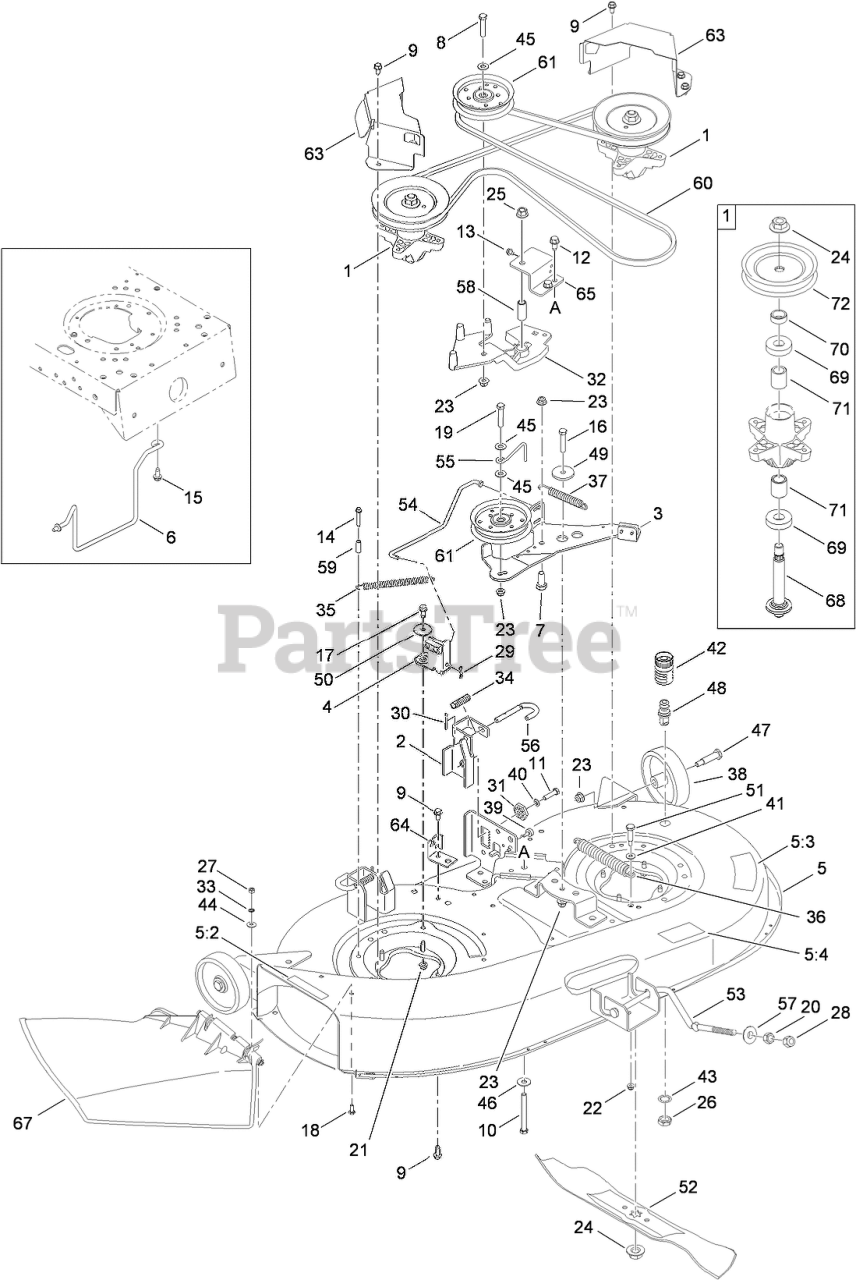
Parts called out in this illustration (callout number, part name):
1	SPINDLE ASM
2	LH HANGER BRACKET ASM
3	BRACKET-IDLER
4	BRAKE ASM
5	DECK ASM (WITH DECALS)
5:2	DECAL-CHUTE
5:3	DECAL-DECK
5:4	DECAL-ROUTING, BELT
6	ROD-KEEPER, BELT
7	SCREW-HH
8	SCREW-HH
9	SCREW-TAP
10	SCREW-HH
11	SCREW-HH
12	SCREW-HWHTF
13	SCREW-TAP
14	SCREW-HWH
15	SCREW-HWH
16	SCREW-HH
17	SCREW-HH
18	SCREW-HH
19	SCREW-HH
20	NUT-HEX
21	NUT-LOCK, FLANGE
22	NUT-LOCK, FLANGE
23	NUT-LOCK, FLANGE
24	NUT-LOCK, FLANGE
25	NUT-LOCK, FLANGE
26	NUT-HEX
27	NUT-HEX
28	NUT-LOCK, HEX (NYLON)
29	PIN-COTTER
30	PIN-COTTER
31	GEAR-ADJUSTMENT, DECK
32	BRACKET-IDLER
33	RETAINER-BOLT
34	SPRING-COMPRESSION
35	SPRING-EXTENSION
36	SPRING-EXTENSION
37	SPRING-EXTENSION
38	WHEEL-DECK, REAR
39	BUMPER
40	WASHER-LOCK
41	WASHER-FLAT
42	ADAPTER-NOZZLE, WATER
43	WASHER-LOCK
44	WASHER-SPRING
45	WASHER-FLAT
46	WASHER-FLAT
47	BOLT-SHOULDER
48	NOZZLE-WATER, DECK
49	SPACER-SHOULDER
50	SPACER-SHOULDER
51	BOLT-SHOULDER
53	ROD-DECK, FRONT ADJUSTMENT
54	ROD-BRAKE
55	ROD-KEEPER, BELT
56	PIN-HANDLE, DECK RELEASE
57	CUP-PIVOT, LIFT
58	NOZZLE-WATER, DECK
59	SPACER
60	BELT-V TYPE
61	PULLEY-IDLER
63	COVER-BELT
64	BRACKET-CABLE, DECK
65	SUPPORT-BRACKET, PIVOT
67	DISCHARGE CHUTE ASM
68	SHAFT-SPINDLE
69	BEARING-BALL
70	SPACER
71	SPACER
72	PULLEY-DECK
